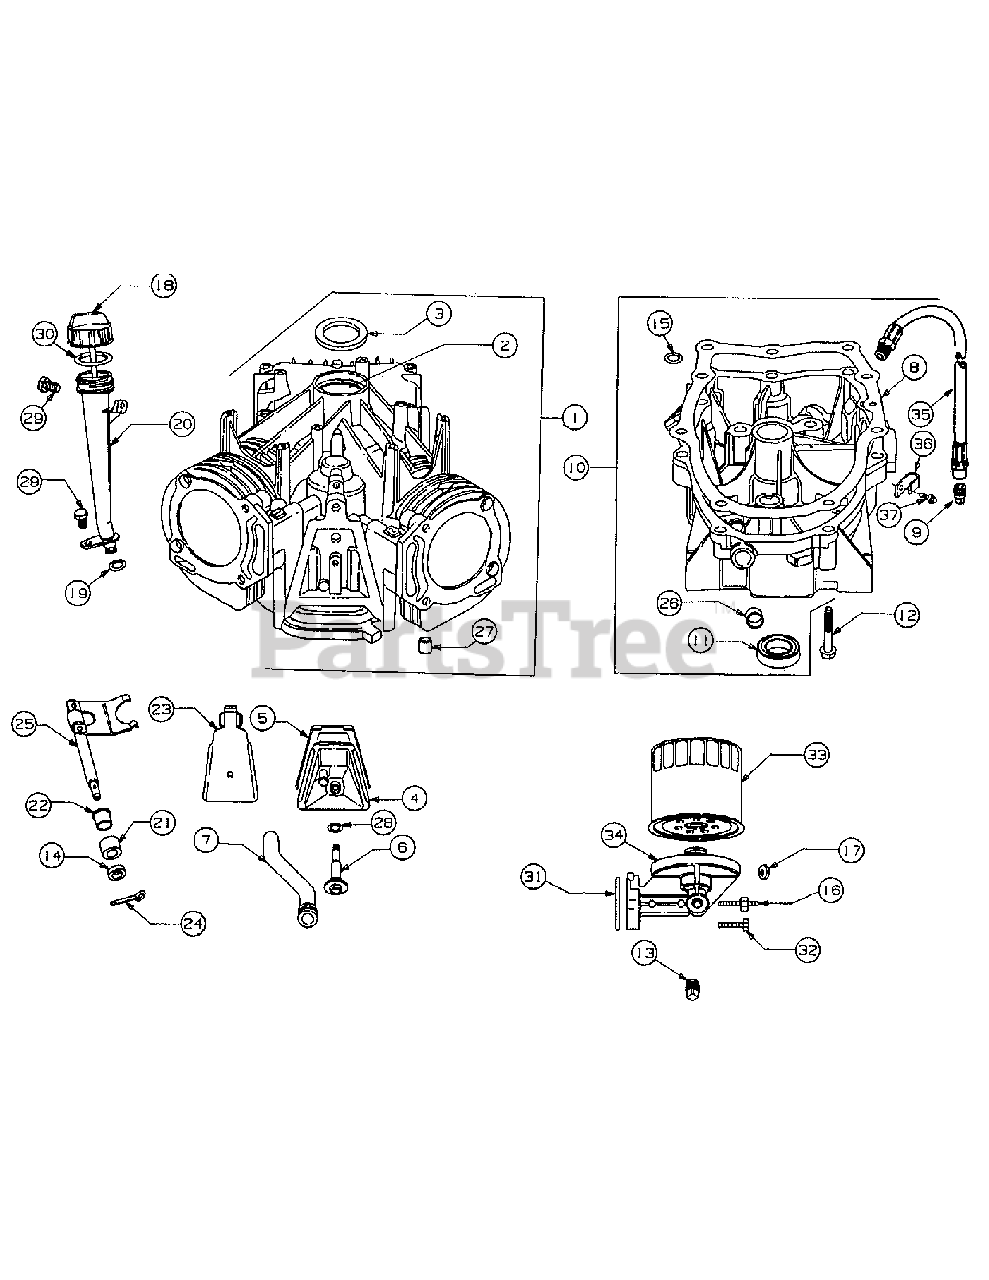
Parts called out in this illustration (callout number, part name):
1	Cylinder Assembly
2	Bearing, Cylinder
3	Seal, Oil
4	Breather Assembly
5	Gasket, Breather
6	Screw, Breather
7	Tube, Breather
8	Gasket, Crankcase Cover
9	Plug, Oil Drain
10	Cover Assembly, Crankcase
11	Seal, Oil
12	Screw, Crankcase Cover
13	Plug, Pipe
14	Seal, Governor Shaft
15	O-Ring, Crankcase Cover
16	Stud, Oil Filter Adapter
17	Washer, Lock
18	Dipstick
19	Seal, Filler Tube
20	Tube, Oil Filler
21	Bushing, Governor Shaft
22	Bushing, Governor Shaft
23	Baffle, Breather
24	Pin, Cotter
25	Fork, Governor
26	Wsher, Governor Shaft
27	Dowel, Crankcase
28	Seal, Breather Screw
29	Screw, Mounting
30	O-Ring
31	Gasket, Oil Filter Adapter
32	Screw, Sem
33	Filter, Oil
34	Adapter, Oil Filter
35	Hose, Oil Drain
36	Clip, Drain Hose
37	Screw, Hex Wash Hd Tapp, 5/16-18 x .50
